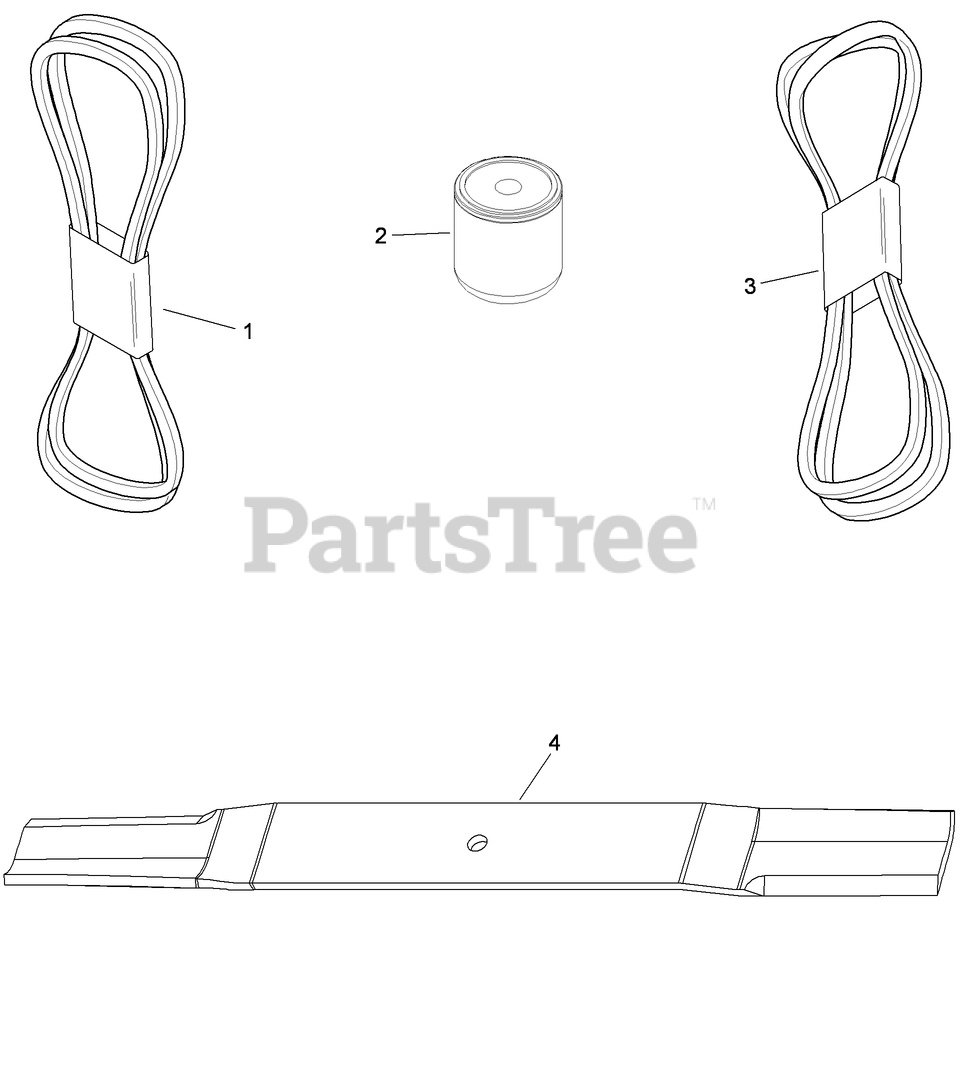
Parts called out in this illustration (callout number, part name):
1	V-BELT
2	FILTER-OIL, HYD
3	V-BELT (72)
4	BLADE-24.75in
